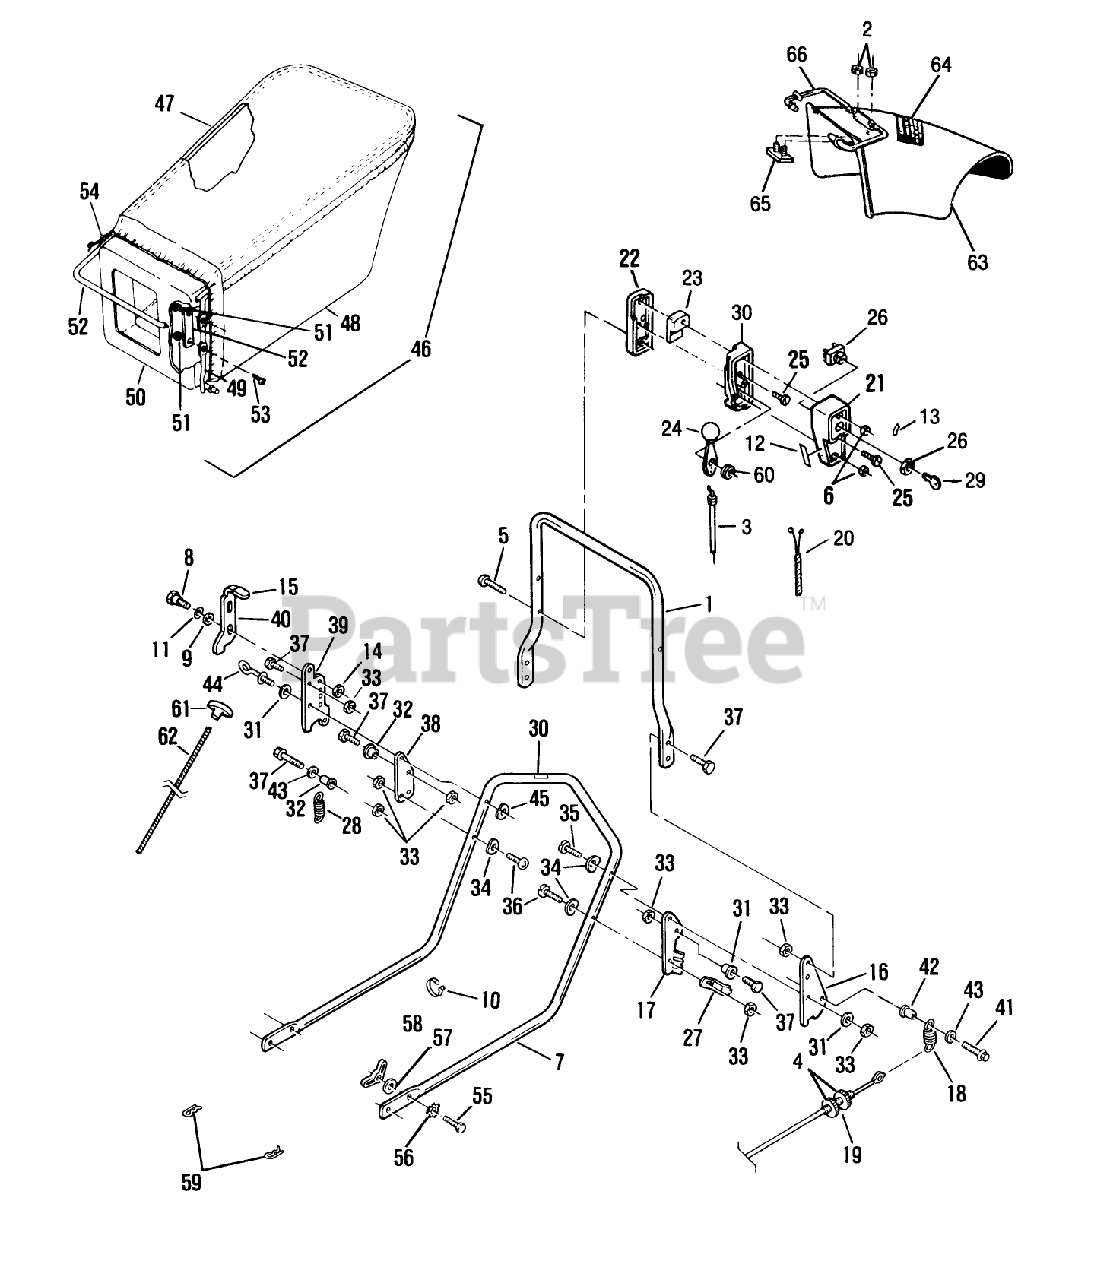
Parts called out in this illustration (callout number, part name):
2	Nut
3	T/CABLE WESCON
5	SCREW
6	NUT C/LOCK E
7	HANDLE SECTION
8	BOLT RB&W
9	WASHER M
14	LOCKNUT E
15	KNOB (S&R)
18	SPRING
19	CABLE AY
21	CASE THROTTLE
22	OUTER CONTROL CASE
24	LEVER&KNOB AY WES
25	SCREW
26	SWITCH AY
33	NUT-LOCK F
34	WASHER-CURVED
35	SCREW LARSON
42	SPACER ROCKFORD
43	WASHER
47	HANGER BAG TROX
50	BAG ADAPTOR PL
51	LOCKNUT E
57	WASHER
58	NUT-WING
60	WASHER-SPRING
61	HANDLE START UM&D
66	LATCH BAR ARGO
